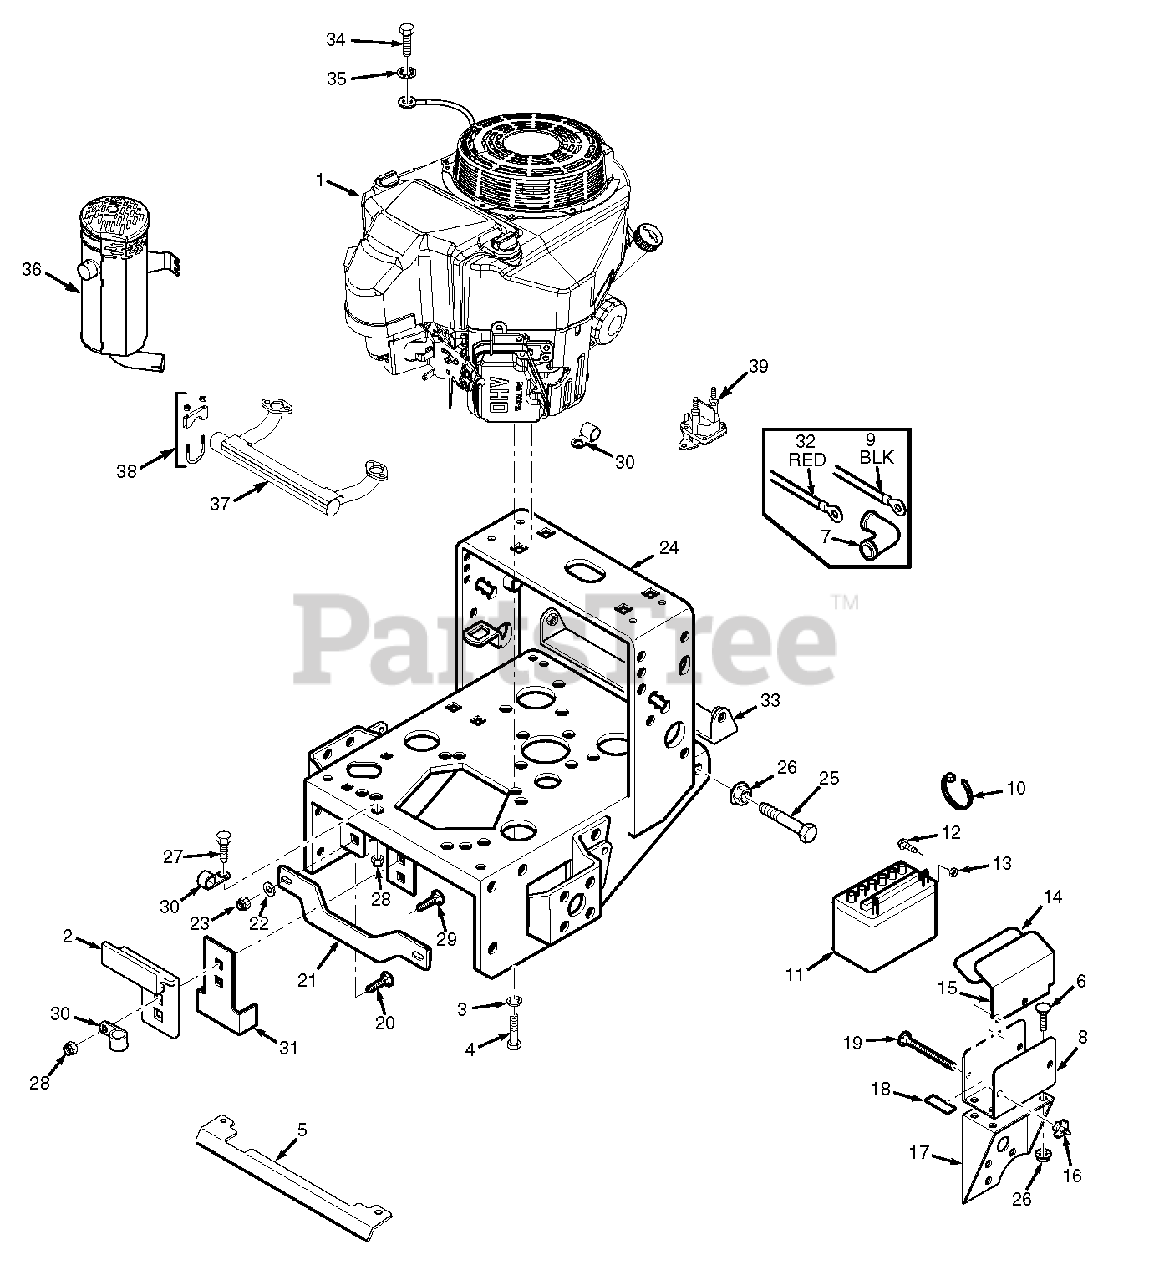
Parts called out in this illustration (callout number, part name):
1	Engine, Kawasaki FS22 (FS651V)
2	Plate, Clutch Bracket
3	Lock Washer 3/8'
4	Bolt, Hex Head 3/8-16 x 1-1/4'
5	Heatshield, 20' Large Frame
6	Carriage Bolt, 5/16-18 x .75'
7	Rubber Boot
8	Battery Box
9	Battery Cable, 31.5' Black
10	Cable Tie
11	Battery (Not Available Through Scag)
12	Bolt, 1/4-20 x 1/2'
13	Nut, 1/4-20
15	Battery Cover
16	Wing Nut, 1/4-20
17	Battery Support
18	Pad, Rubber
19	Bolt, 1/4-20 x 6' Carriage
20	Carriage Bolt, 3/8-16 X 1-1/4'
21	Brace, 20' Large Frame
22	Flat Washer .391 x .938 x .105
23	Nut, 3/8-16 Elastic Stop
24	Engine Deck, 20' Wide, w/decals
25	Bolt, 5/16-18 x 2' Hex Head
26	Nut, 5/16-18 Serr. Flange
27	Hex Head Bolt, 5/16-18 x .75'
28	Nut, 5/16-18 Elastic Stop
29	Carriage Bolt, 5/16-18 x 1'
31	Clutch Bracket
32	Battery Cable, 25' Red
32	Battery Cable, 18' Red
33	Pulley Guard, 20' Frame
34	Bolt, Hex Head M8-1.25 x 16
35	Lockwasher, 5/16' Ext. Tooth
36	Muffler
37	Exhaust Manifold
38	Clamp, Muffler 1-1/2' Dia.
39	Solenoid
